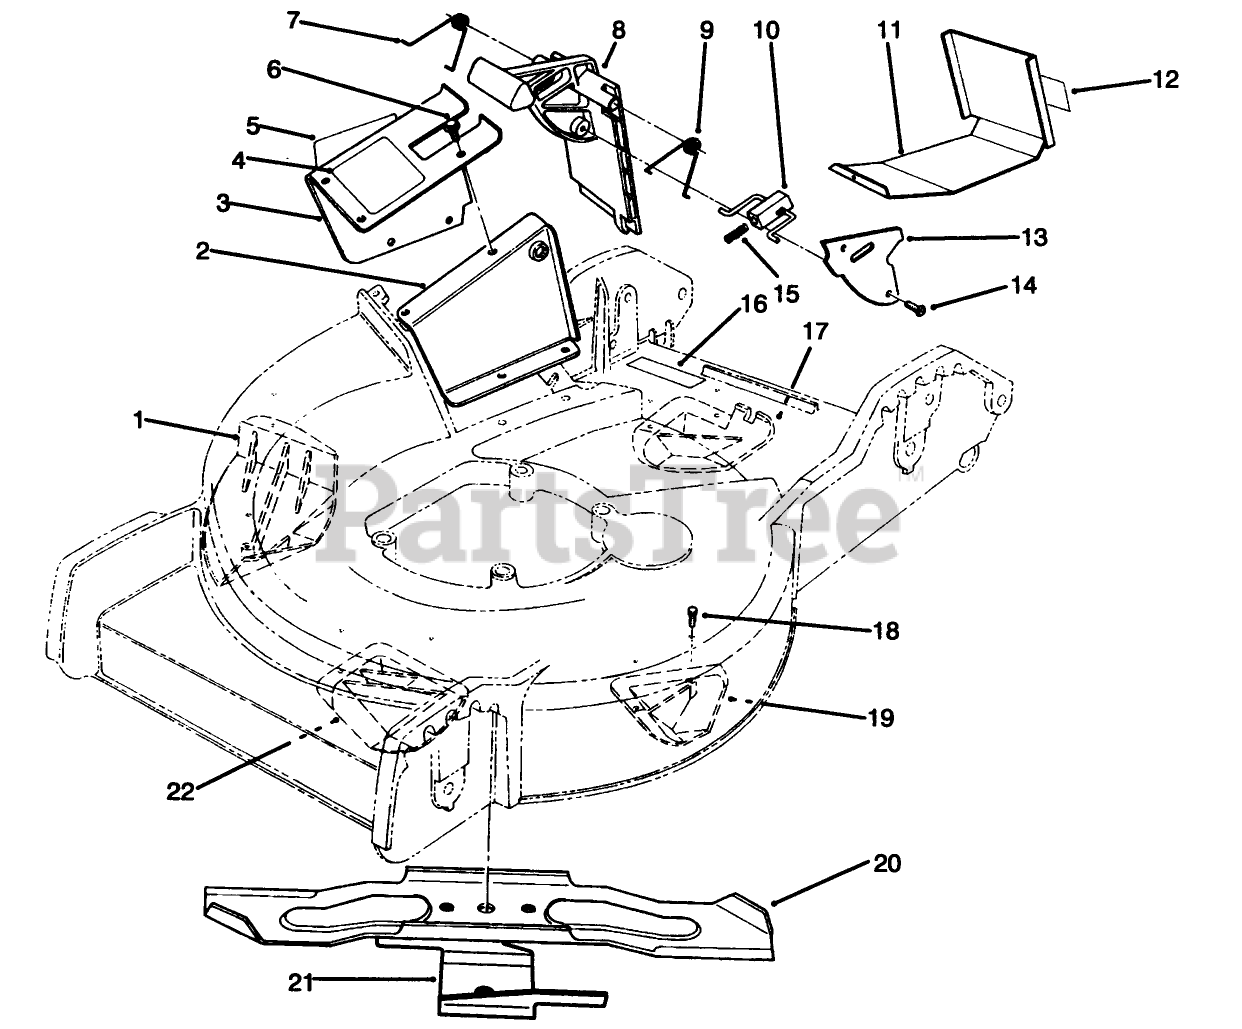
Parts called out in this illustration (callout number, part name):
1	KICKER
2	Tunnel-Inner
3	Tunnel-Outer (Incl. Ref. #4 & 5)
4	DECAL - CAUTION DOOR
5	DECAL-DANGER
6	SCREW-HWH
7	SPRING-DOOR, RH
9	LH DOOR SPRING
10	LATCH-DOOR
11	Discharge Plug Assembly (Incl. Ref. #12)
12	DECAL - WARNING
13	DOOR COVER
15	SPRING-COMPRESSION, LATCH
16	DECAL - CAUTION
17	KICKER
18	SCREW-PPH
19	KICKER
20	Blade-18"
21	18 ACCELERATOR
22	KICKER
